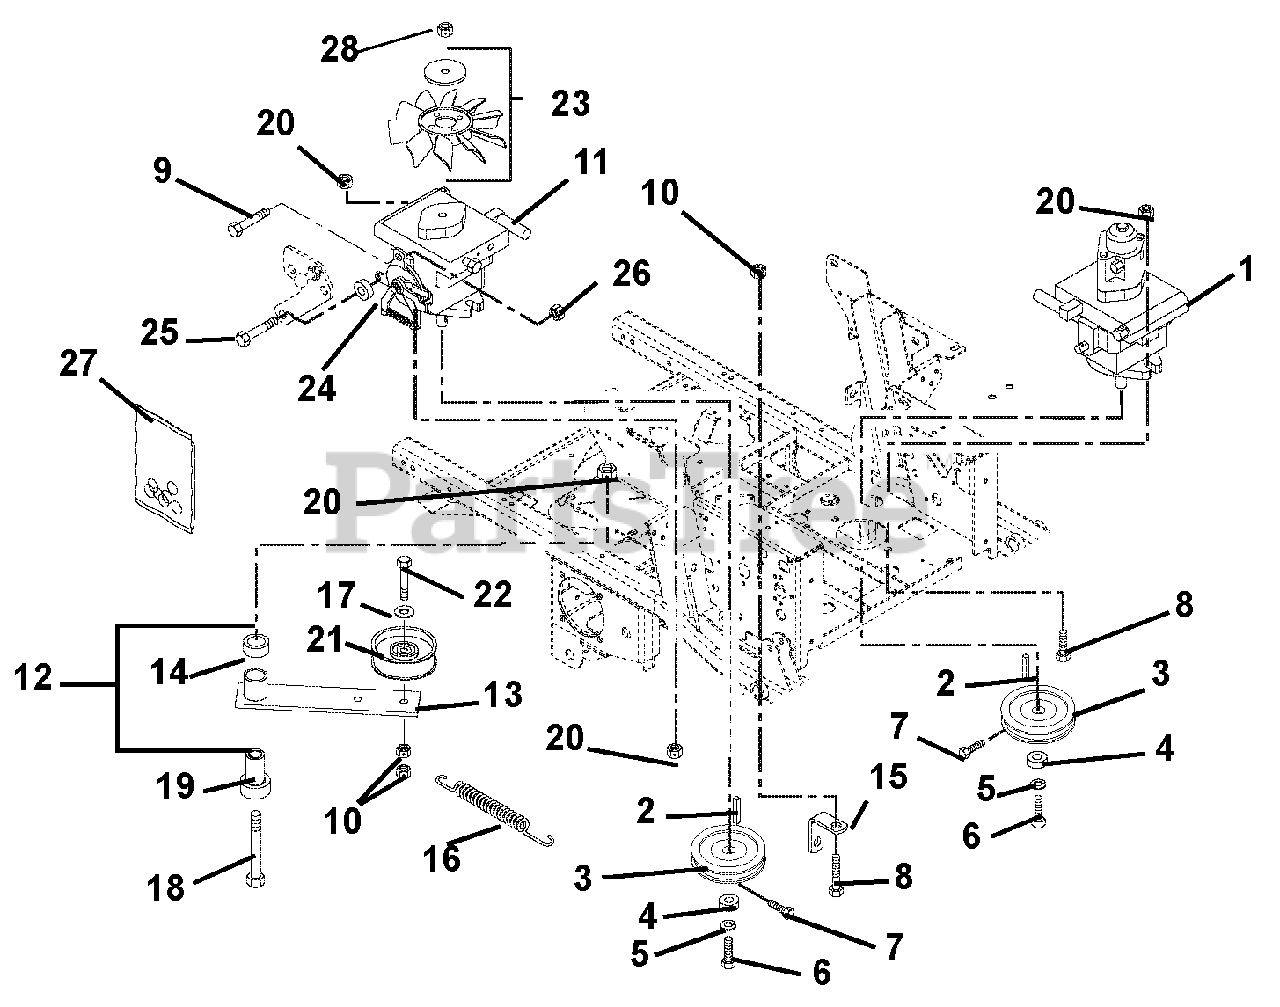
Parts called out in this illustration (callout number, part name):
1	Pump, Hydraulic with Auxiliary (992213, 217) (page 17)
2	Key, Square 5 x 5 x 30mm Plain
3	Sheave, Poly V .671 x 4.125
4	Washer, Flat Steel .281 x 1.000 x .063
5	Washer, Locking .25 x .062
6	Bolt, Hex M6 x 1.0 x 12 YZ EP30
7	Screw, Socket Head .25-20 x .50 YZ EP80
8	Bolt, Hex .50-13 x 1.50 Grade 5
9	Bolt, Hex .31-18 x .75 Grade 5
10	Nut, Locking Top Flange .38-16
11	Pump, Hydraulic BDP-21 with Thru Fan (page 19)
12	Assembly, Idler Arm Guard Drive (Includes 13 & 14)
13	Weldment, Idler Arm Ground Drive
14	Bushing, 1.00 x 1.125 x 1.936
15	Anchor, Spring Idler
16	Spring, Tension
17	Washer, Flat Steel .39 x .75 x.125
18	Bolt, Hex .50-13 x 3.50 Grade 5
19	Bearing, Pedestal
20	Nut, Locking Top Flange .50-13
21	Idler, Flat 4.00 x .38
22	Bolt, Hex .38-16 x 2.25 Grade 5
23	Fan, Cooling
24	Spacer .318 x .43 x .375
25	Bolt, Hex .31-18 x 1.25 Grade 5
26	Nut, Locking Top Flange .31-18
27	Kit, Pump Seal (BDP-21A) (One kit required for each pump)
28	Nut, Center-Lock .31-24
